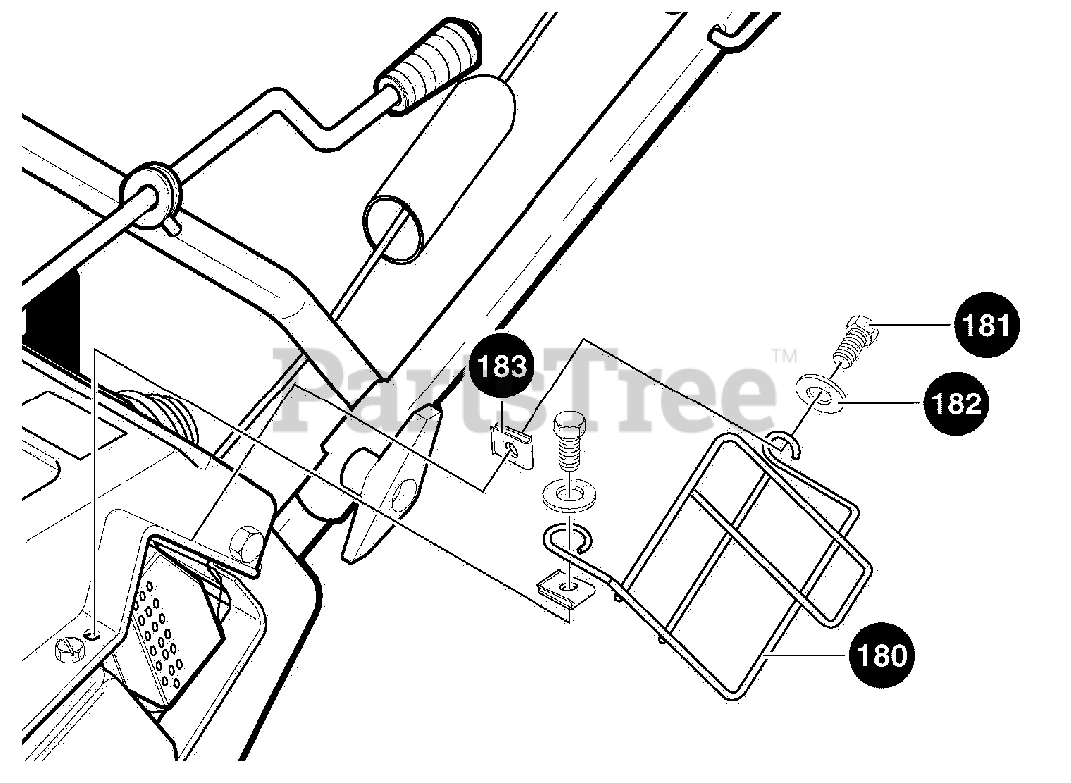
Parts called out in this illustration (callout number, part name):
180	GUARD, MUFFLER
181	SCREW
182	WASHER, FLAT
